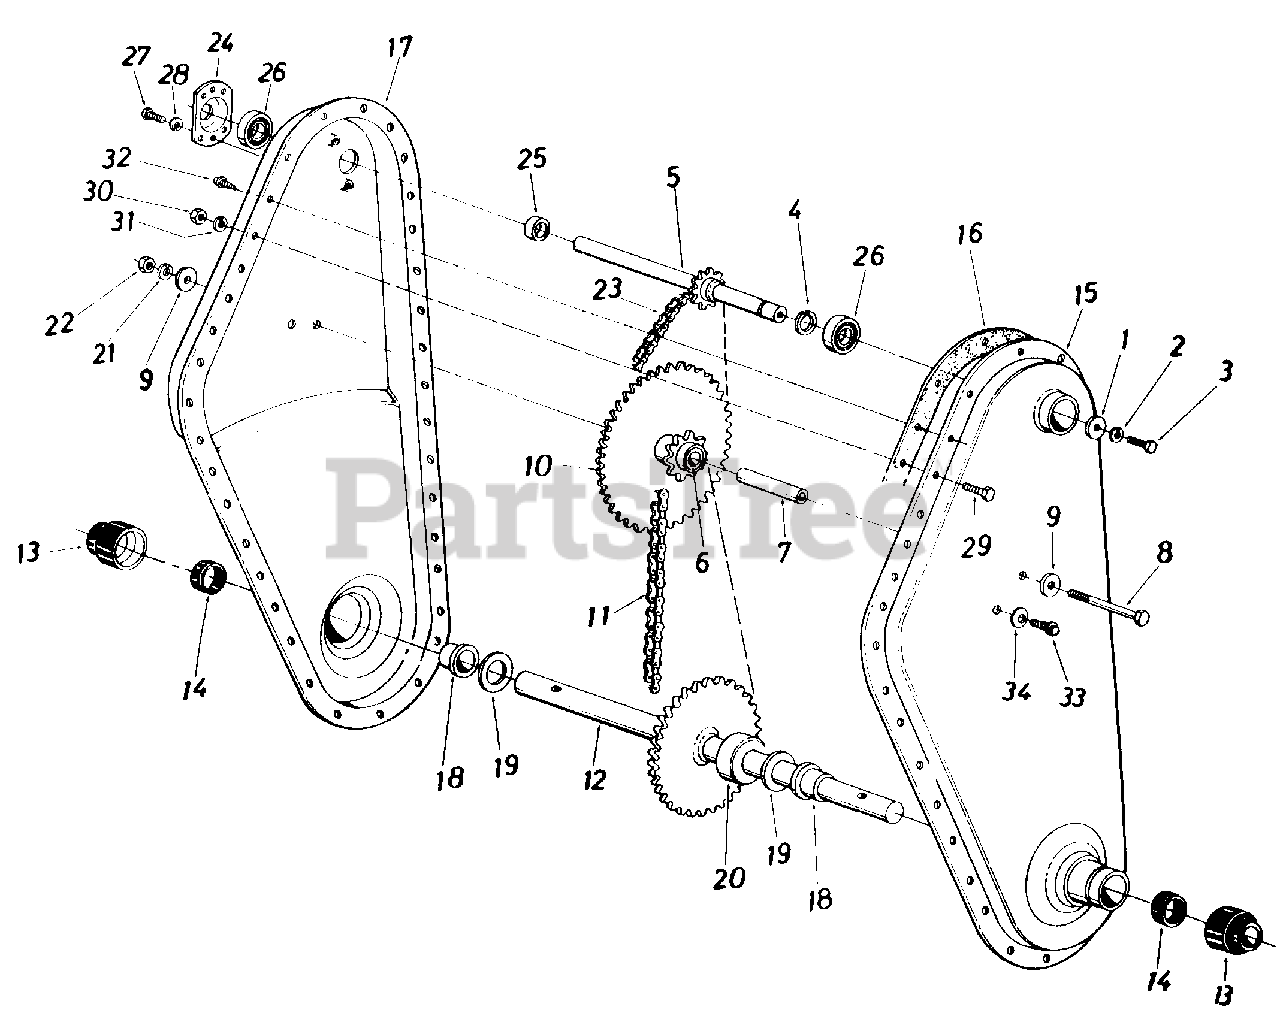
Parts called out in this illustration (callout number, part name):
1	Fl-Wash. 1/4" I.D. x .93" O.D. x . 1 20
2	L-Wash. 1/4" I.D.*
3	Hex Bolt 1/4-28 x .62" Lg. w/ Patch
4	External Snap Ring-5/8" Dia.
5	Input Shaft Ass'y.
6	Bearing 5/8" I.D. x 3/4" O.D. x 1.860" Lg.
7	Sprocket Hub Tubing 3/8" I.D. x 5/8" O.D. x 1.90
8	Hex Bolt 3/8-24 x 2.75" Lg.
9	Fl-Wash. 3/8" I.D. x 1.25 O.D. x .10
10	Sprocket Ass'y.
11	#50 Chain 5/8" Pitch x 46 Links Endless
12	Tine Shaft Ass'y.
13	Dust Cup
14	Seal Ring Single Lip, Springless
19	Fl-Thrust Wash. 1.0" I.D. x .03 Thk.
20	Step Spacer
21	L-Wash. 3/8" I.D.*
22	Hex Nut 3/8-24 Thd.*
23	#35 Chain 3/8" Pitch x 52 Links Endless
24	Bearing Housing 1.38" I.D.
25	Spacer
26	Ball Bearing .625" I.D. x 1.38" O.D. x .437
27	Hex Wash. SF-Tap Scr. 1/4-20 x .50" Lg.
28	L-Wash. 1/4" I.D.*
29	Hex Bolt 5/16-18 x .75" Lg.*
30	Hex Nut 5/16-18 Thd.*
31	L-Wash. 5/16" I.D.*
32	Hex Wash. SF-Tap Scr. 1/4-20 x .50" Lg.
33	Hex Wash. Hd. Tap Scr. 1/4-20 x .38" Lg.
34	Bell-Wash. .265" I.D. x .75" O.D.
